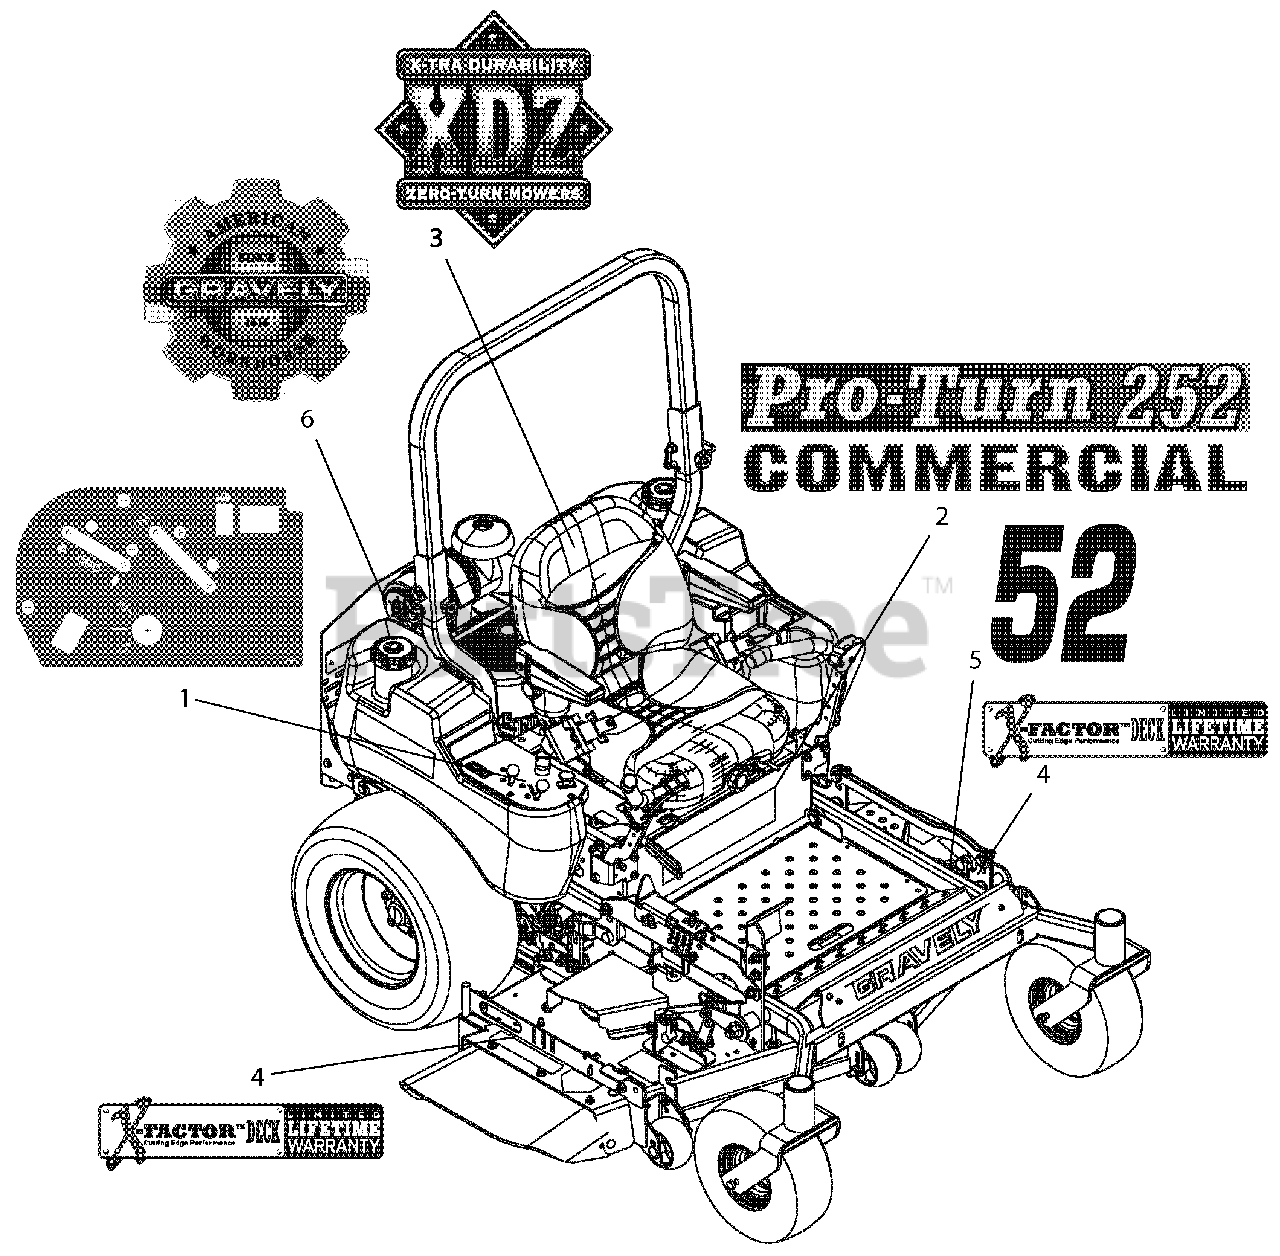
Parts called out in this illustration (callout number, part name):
1	DECAL, CONTROL PANEL NON-EFI
2	DECAL, PROTURN 252
3	DECAL, XDZ
4	DECAL, X-FACTOR DECK
5	DECAL, 52"
6	DECAL, GRAVELY HERITAGE-LARGE
